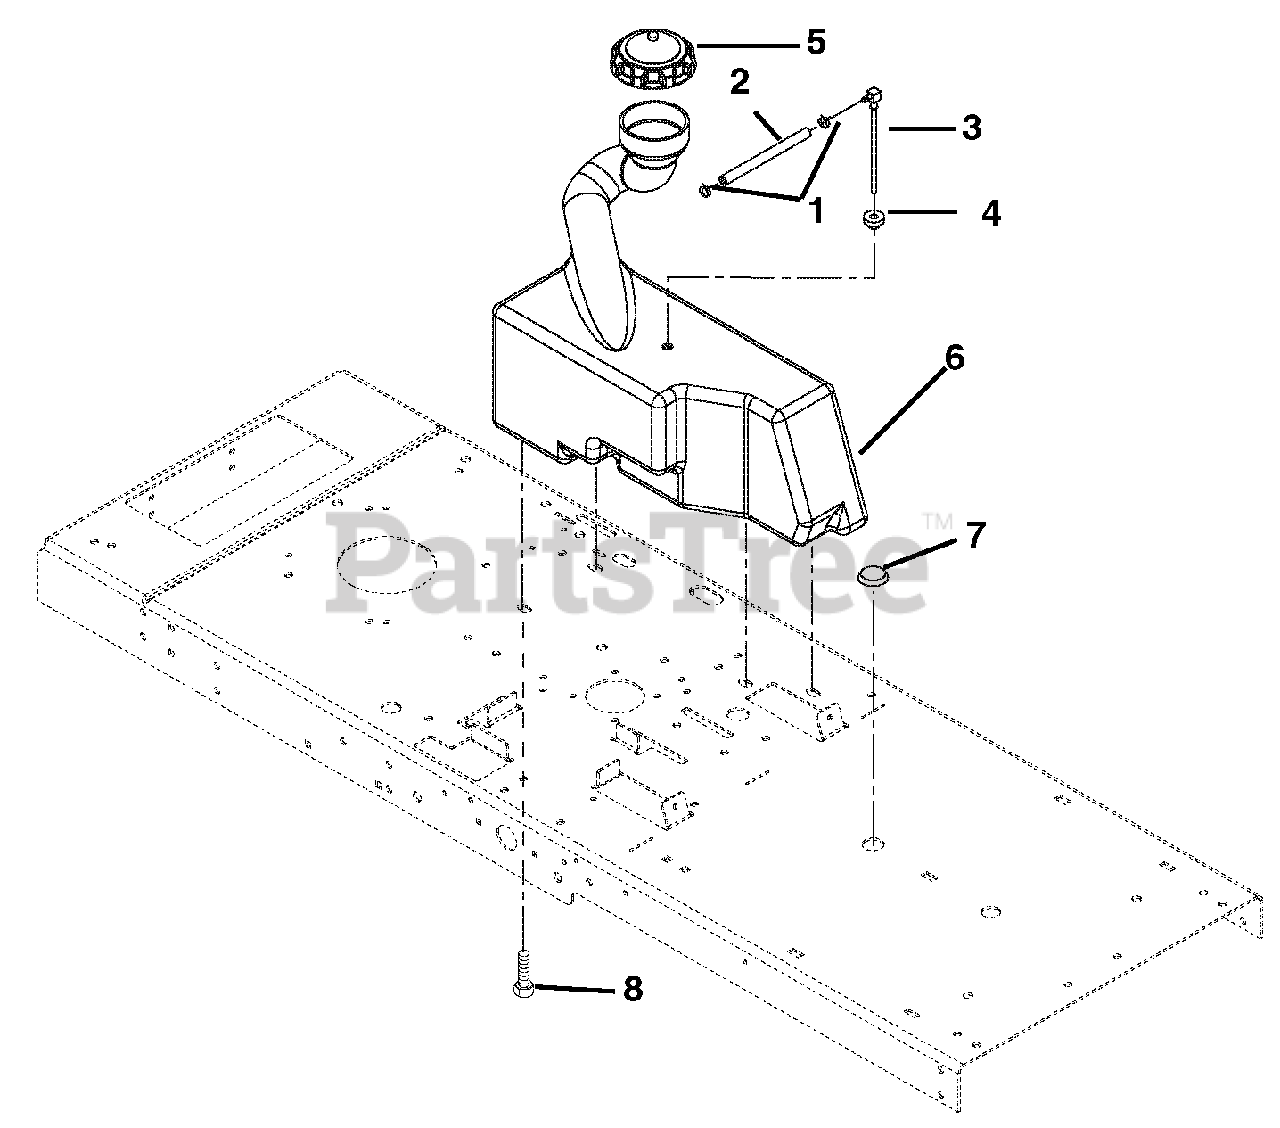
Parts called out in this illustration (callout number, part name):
1	Clamp-Hose-Wire .490/.510 x .116
2	Hose-Fuel .25 I.D. x 17.5" Long
3	Fitting-Tank
4	Bushing
5	Cap-Fuel
6	Fuel-Tank
7	Plug-Button
8	Bolt-Hex .312-18 x .75 Grade 5
